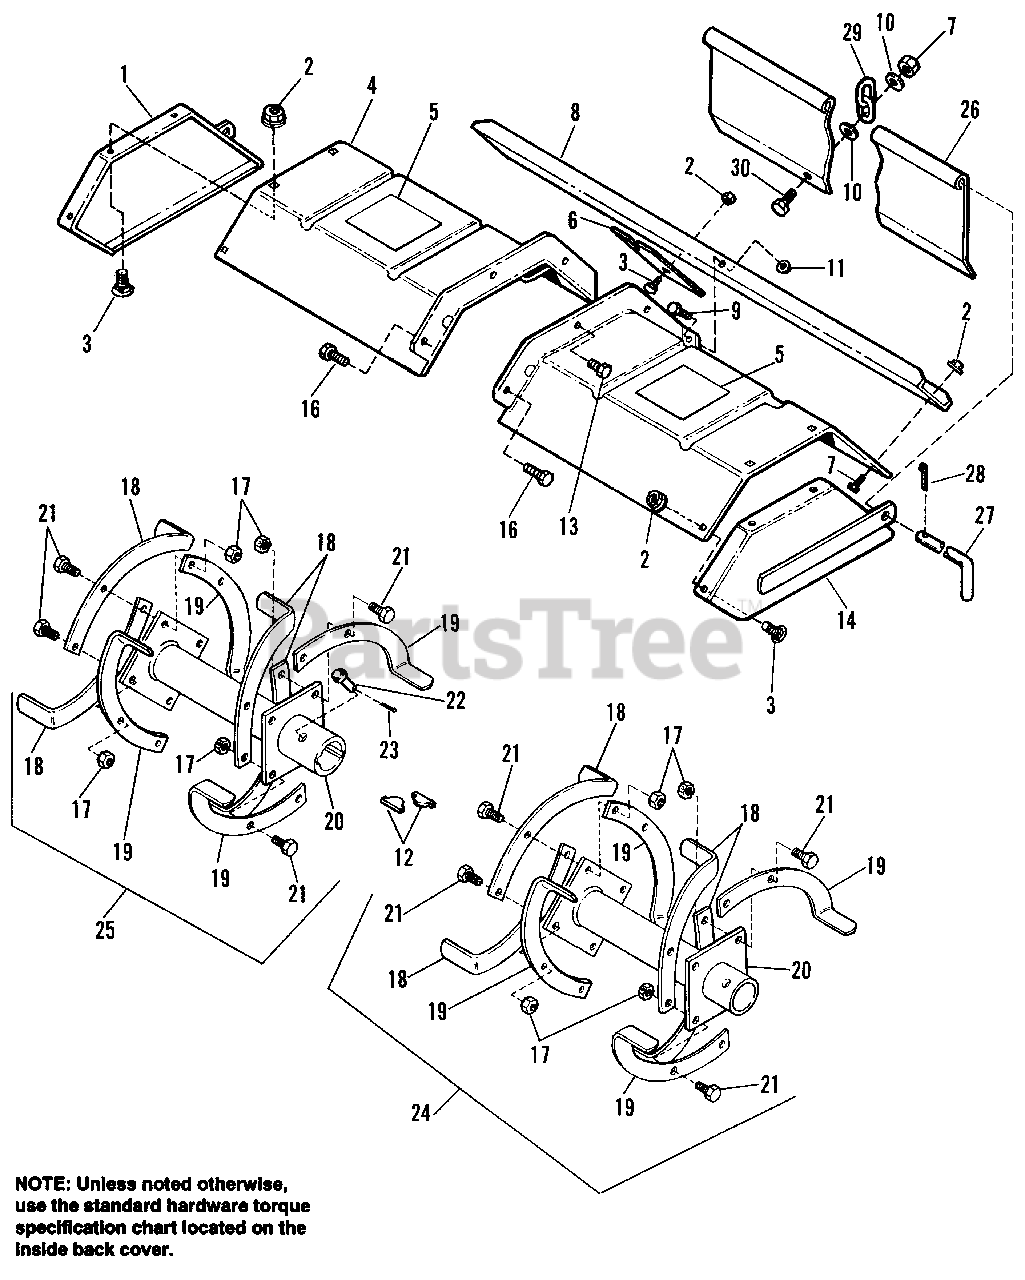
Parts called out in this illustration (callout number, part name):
1	PLATE, End, R.H.
2	LOCKNUT, Flange, 5/16-18
3	CARRIAGE BOLT, 5/16-18 x 5/8
4	DEFLECTOR ASSY., R.H.
5	DECAL, Safety
7	NUT, Hex, Flange Hd., 1/4-20
8	CHANNEL, Brace, Pivot
9	CAPSCREW, Hex, 3/8-16 x 1
10	WASHER
11	NUT, Hex, Flange Lock, 3/8-16
13	SCREW, Hex, Whizlock, 3/8-16 x 3/4
14	PLATE, End, L.H.
16	SCREW, Hex, Whizlock, 3/8-16 x 1
17	LOCKNUT, Hex, 7/16-20
18	BLADE, Tine, R.H.
19	BLADE, Tine, L.H.
20	HUB & PLATE ASSY.
21	CAPSCREW, Hex Hd., 7/16-20 x 1-1/2
23	PIN, Cotter, 1/8-3/4
24	BLADE ASSY., L.H.
25	BLADE ASSY., R.H.
27	ROD, Deflector
28	PIN, Cotter
29	CHAIN
30	CAPSCREW, Hex Hd., 1/4-20 x 7/8
